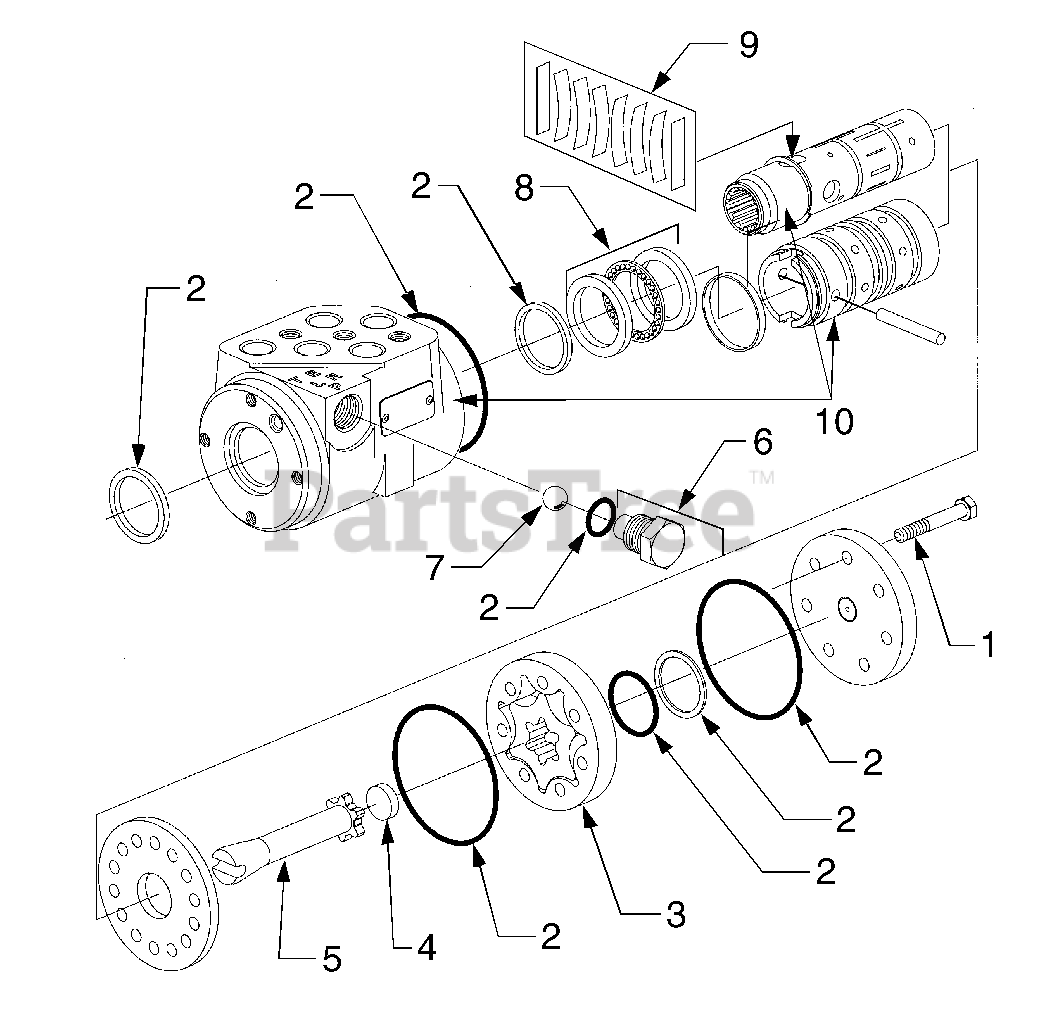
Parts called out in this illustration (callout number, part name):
1	Screw, Hex Cap, 1.57" Lg.
2	Seal Kit
3	Gerotor Assembly
4	Spacer, .240 Lg.
6	Plug, Manual Check
7	Ball, Manual Check
9	Spring Kit, Centering
10	Spool, Sleeve and Housing
